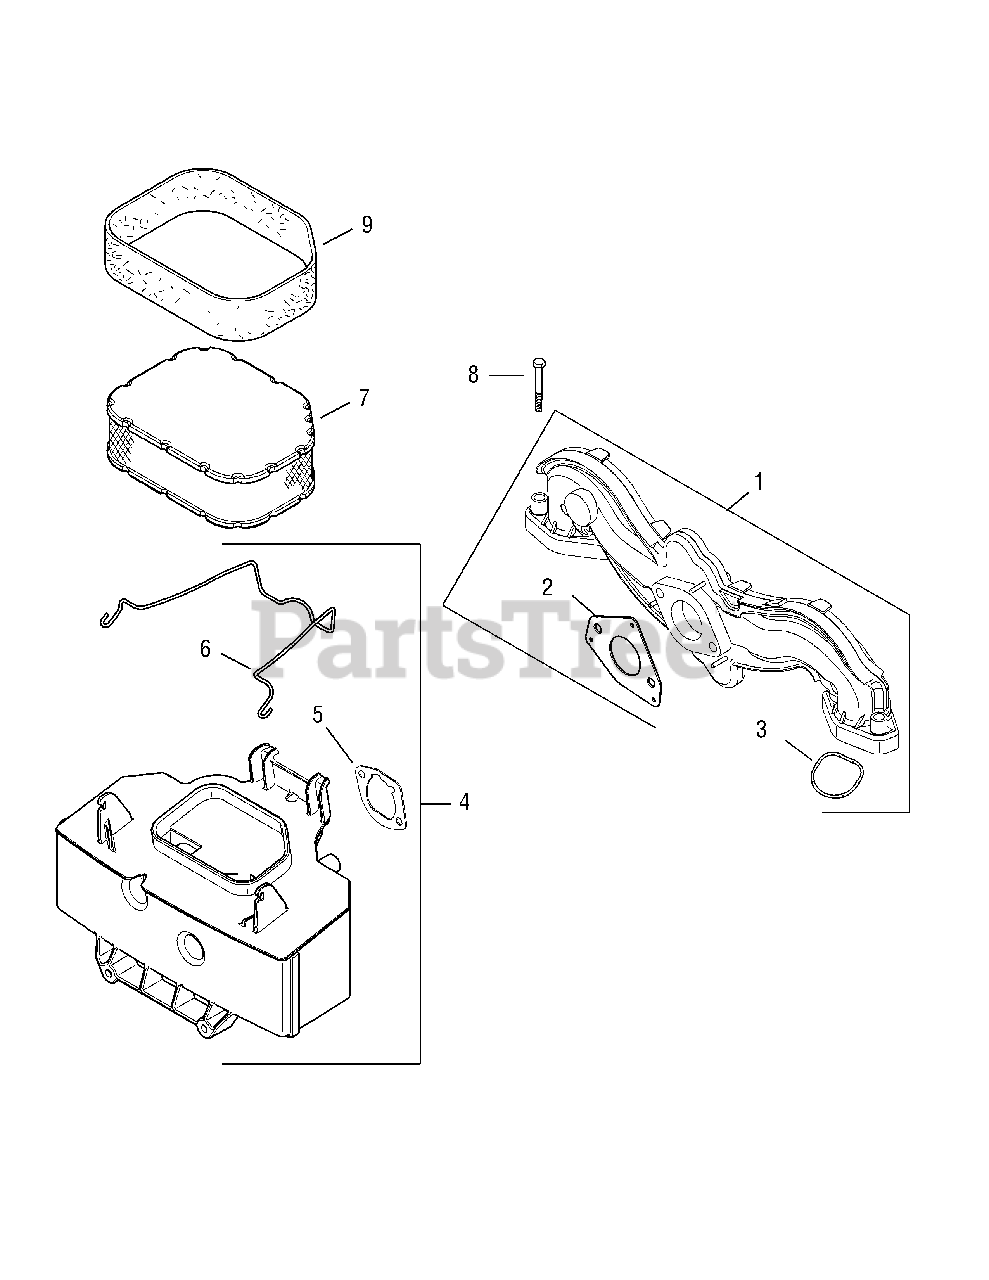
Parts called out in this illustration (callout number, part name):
1	Intake Manifold (Inc. 2 & 3)
2	Carburetor Gasket
3	Intake Port O-Ring
4	Air Cleaner Base (Inc. 5 & 6)
5	Air Cleaner Base Gasket
6	Air Cleaner Element Latch
7	Air Cleaner Element
8	Hex Flange Screw, M6 x 1.0 x 40
9	Element Pre-Cleaner
